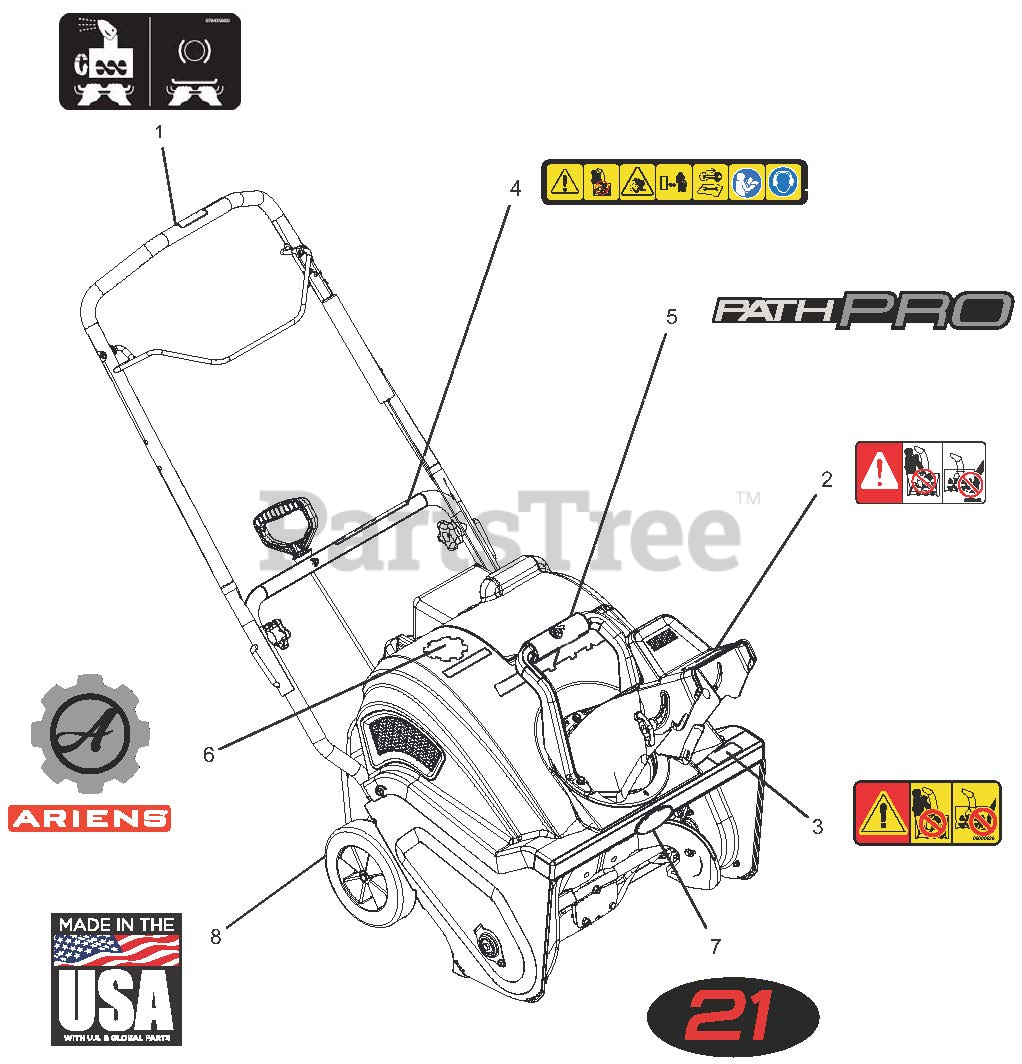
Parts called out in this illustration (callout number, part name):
1	DECAL-AUGER/IMPELLER BAIL
2	DECAL, DANGER
3	DECAL, DANGER SINGLE STAGE
4	DECAL, WARNING
5	DECAL, COWL - PATHPRO
6	DECAL, ARIENS GEAR/BRAND, SS
7	DECAL, COWL - PATHPRO 21
8	DECAL, MADE IN USA
